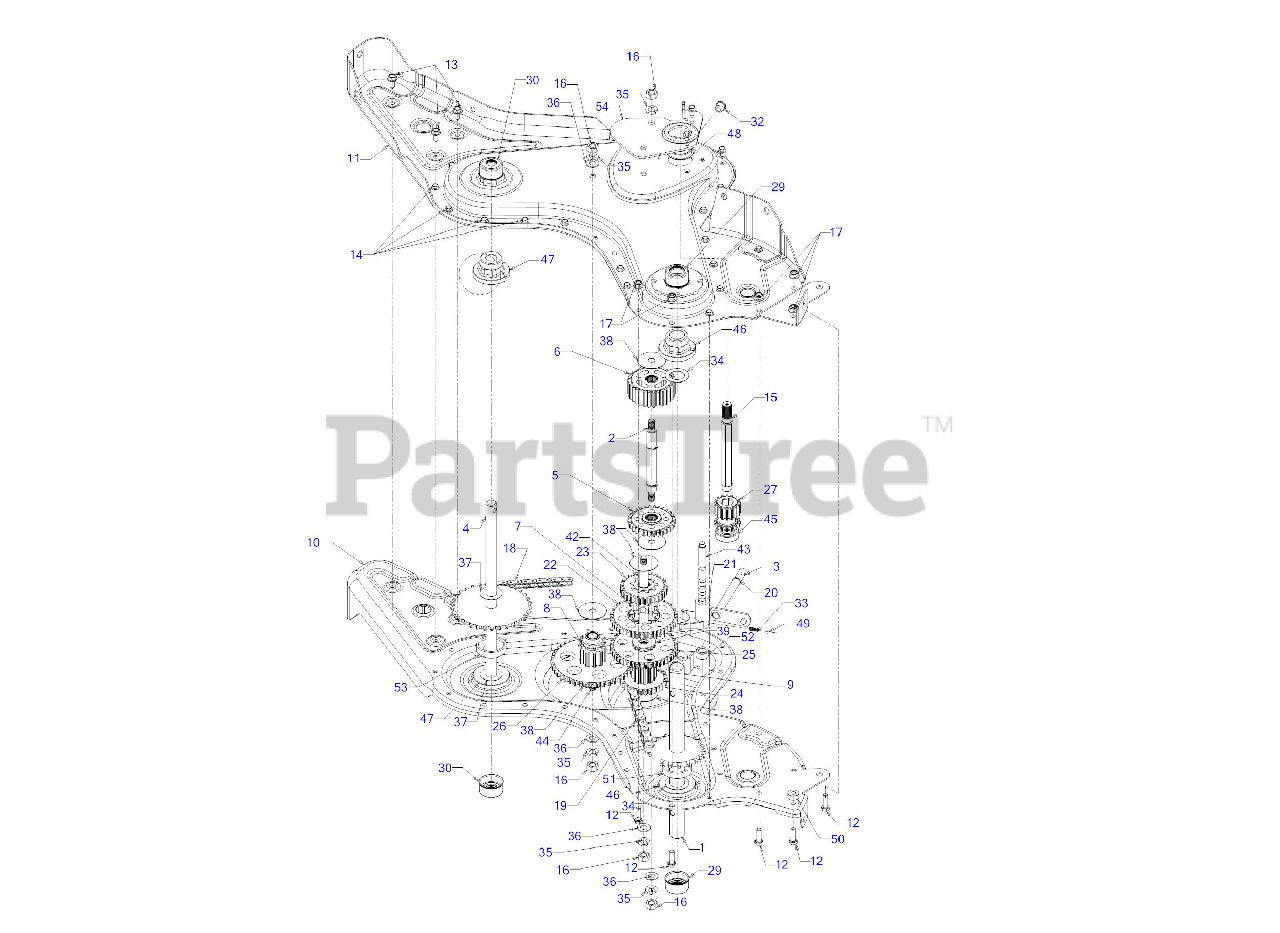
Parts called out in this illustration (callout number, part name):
1	TINE SHAFT ASSEMBLY W/18T
2	JACK SHAFT ASSEMBLY
2	RETAINING RING
2	JACK SHAFT
3	INPUT SHAFT ASSEMBLY
4	33T WHEEL SHAFT ASSEMBLY
5	30T REVERSE IDLER GEAR ASSEMBLY
5	NEEDLE BEARING
6	30T FORWARD IDLER GEAR ASSEMBLY
6	NEEDLE BEARING
7	9T TINE INPUT SPROCKET ASSEMBLY
7	NEEDLE BEARING
8	10T WHEEL INPUT SPROCKET ASSEMBLY
8	SLEEVE BEARING
9	11T GEAR ASSEMBLY
9	NEEDLE BEARING
10	CHAIN CASE HOUSING (RH)
11	CHAIN CASE HOUSING ASSEMBLY (LH)
12	SCREW 5/16-18 x 1.0 GR5
13	SCREW 5/16-18 x .750
14	SCREW 1/4-20X.625
15	INPUT SHAFT
16	HEX NUT 7/16-20
17	FLANGE LOCK NUT 5/16-18
18	#420 CHAIN-1/2 PITCH
19	CHAIN-54 LINKS 5
20	SNAP RING FOR .500
21	CLUTCH COLLAR
22	SPUR GEAR 44T
23	SPUR GEAR 30T
24	SPUR GEAR 30T
25	SPUR GEAR 44T
26	SPUR GEAR 44T
27	SPUR GEAR 16T
29	SHAFT SEAL
30	SHAFT SEAL
32	TAPER CAP PLUG
33	COMPRESSION SPRING
34	FLAT WASHER
35	LOCK WASHER 7/16
36	FLAT WASHER.469 ID x .88 OD
37	THRUST WASHER
38	THRUST WASHER
39	FLAT WASHER .635X1.585X.062 HDN
42	JACK SHAFT-.625 x 5.00 x 7/16-20
43	DETENT SHAFT
44	JACKSHAFT
45	BALL BEARING
46	BEARING
48	BALL BEARING
49	DETENT BALL
52	SPACER-.505 1D
54	GEAR POSITIONER BRACKET
